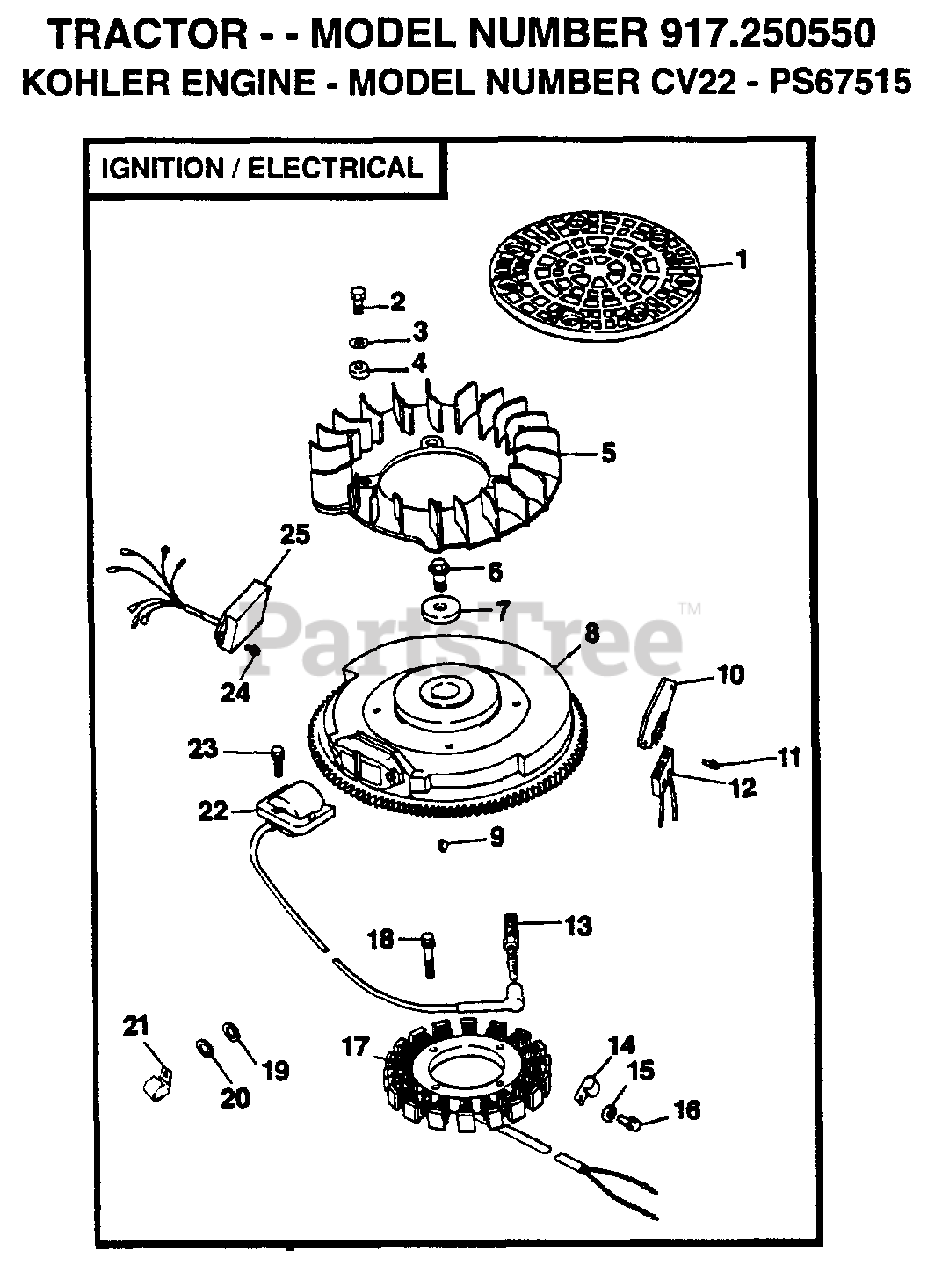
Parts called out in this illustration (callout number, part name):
1	SCREEN, GRASS
3	WASHER
6	SCREW
8	FLYWHEEL ASSY
9	KEY
10	RECTIFIER-REGULATOR
12	CONNECTOR
18	SCREW
19	WASHER, PLAIN 1/4
20	WASHER
22	MODULE, IGNITION
23	SCREW
24	SCREW HEX FLANG M4 X .7 X 10
25	No Desciption for Part
